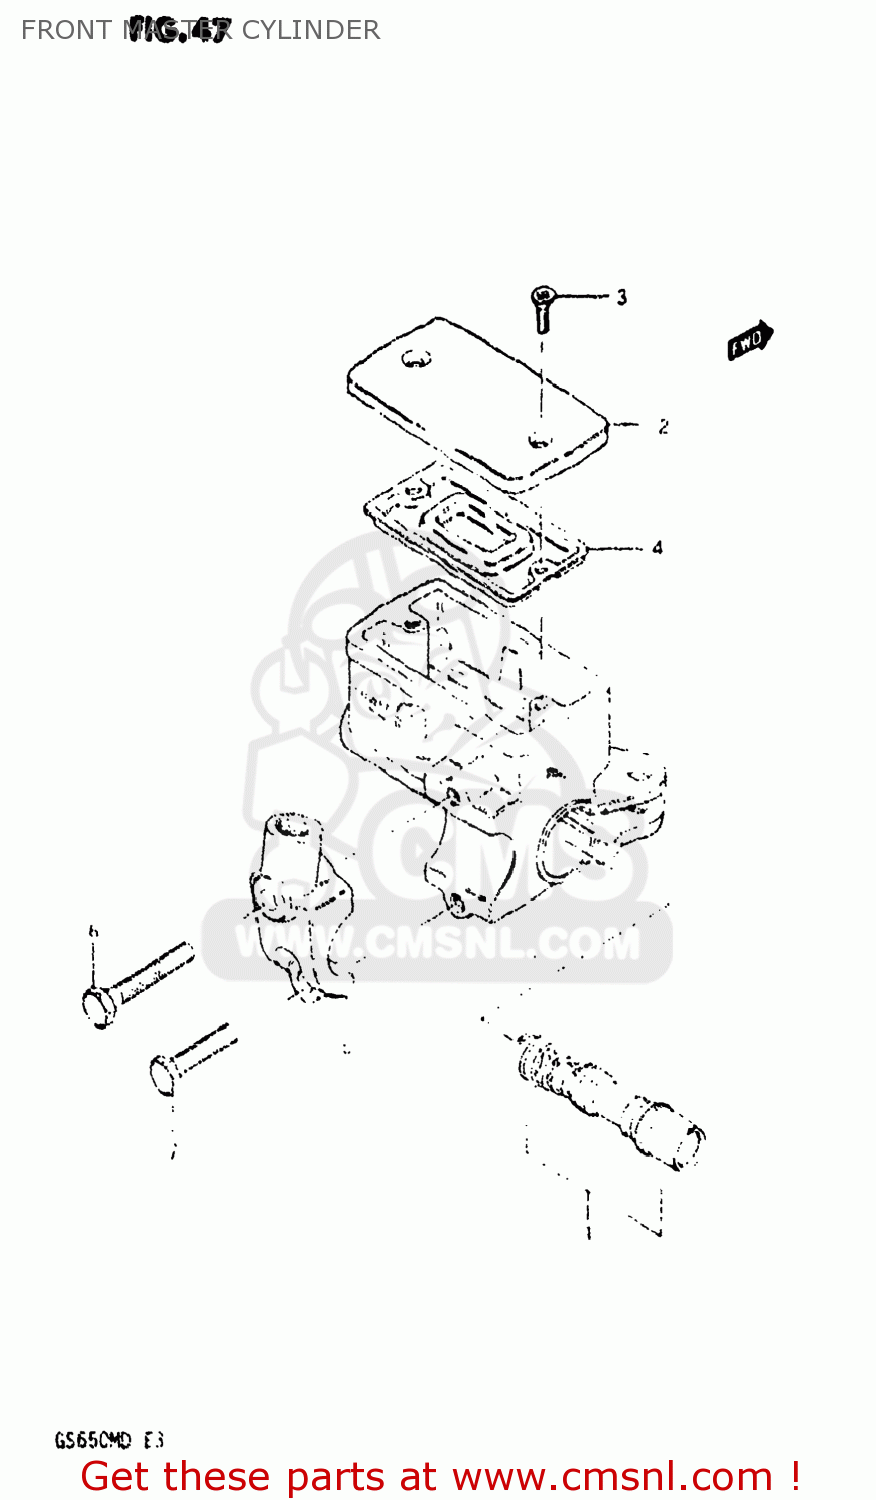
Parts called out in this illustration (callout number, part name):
1	PISTON & CUP SET
2	CAP,MASTER CYLINDER,REAR
3	SCREW,RESERVOIR CAP
4	DIAPHRAGM,MASTER CYLINDER
5	HOLDER
6	BOLT,MASTER CYLINDER H
7	BOLT,MASTER CYLINDER H
